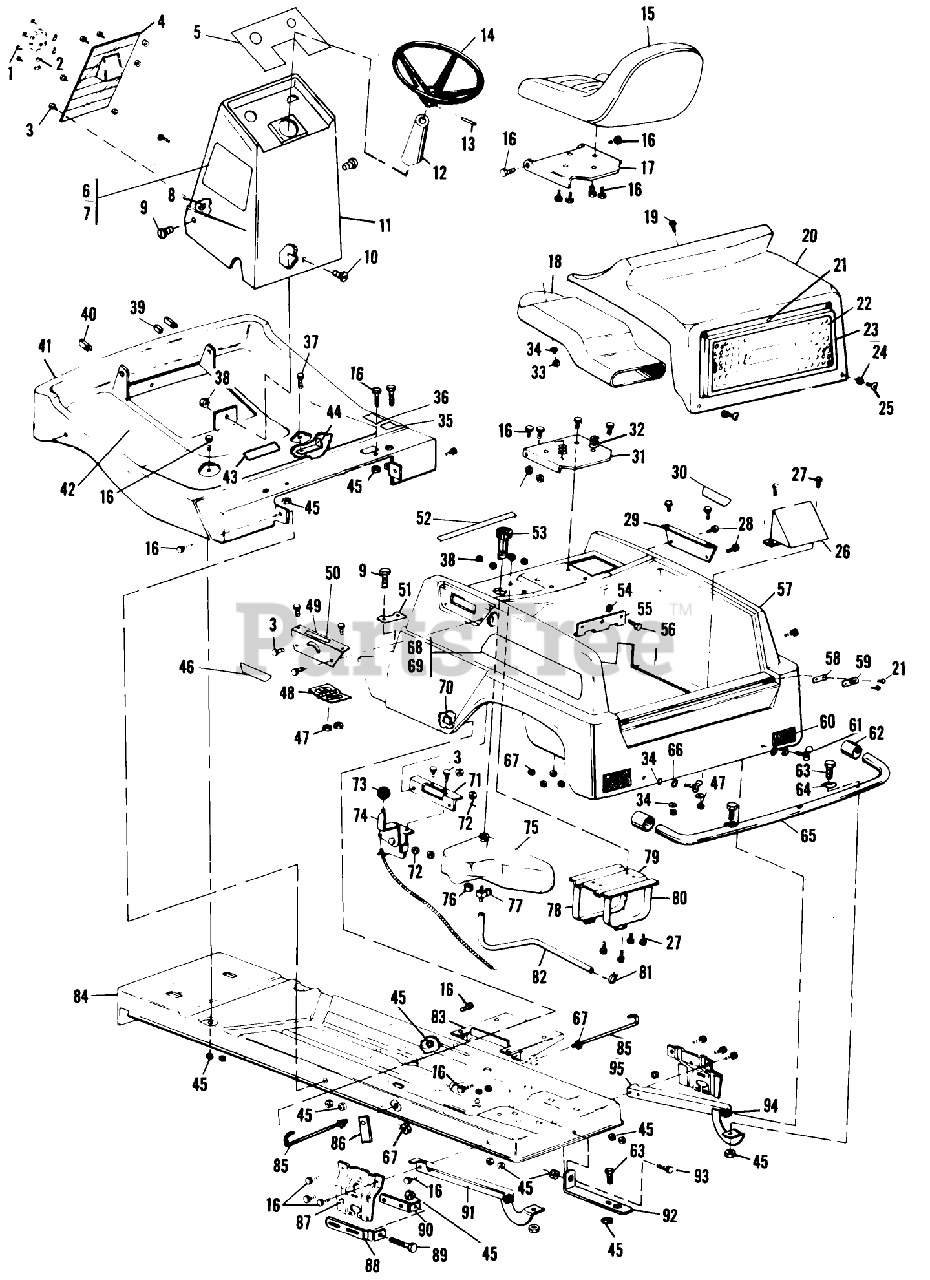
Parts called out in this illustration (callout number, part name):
4	Headlamp Holder, Front Console
9	*Screw, Truss Hd, 1/4-20 Thd
10	Screw, Taptite, 5/16-18 x 3/4 In.
13	Roll Pin
16	Bolt 5/16-18 x
18	Duct, Air Intake
19	*Screw, Truss Hd, 1/4-20 x 1 In.
23	Rim, Screen Retainer
26	Exhaust Extension
27	*Screw, Hex Hd, 1/4-20 x 5/8 In.
28	Rivet, 3/16 x 9/32 In .
33	Nut-Nylok
34	Washer
35	Decal, Parking Brake
37	Bolt 5/16-18 x 1
38	Nut 1/4-20 Keps
39	Panel Clip
41	Floor Pan
45	Nut-Nylok
47	Nut-Nylok
51	Backup Plate
54	Washer
56	Rivet, 3/16 x 3/8 In.
63	Bolt 5/16-18 x 1/2
64	Washer, Formed
67	Nut 5/16-18 Keps
70	Pad, Body Guide
71	Bracket, Throttle Mount
72	*Nut, Keps, No. 8
79	Plate, Gas Tank Support
83	Battery Rack Assembly
84	Main Frame
85	Body, Rod Guide
86	Bracket, Upstop
89	Bolt Hex 5/6-18 X 2-1/2
90	Chain Adjustment, Inner
93	Bolt Hex 5/16-18
96	Service Rod (Not Illust.)
